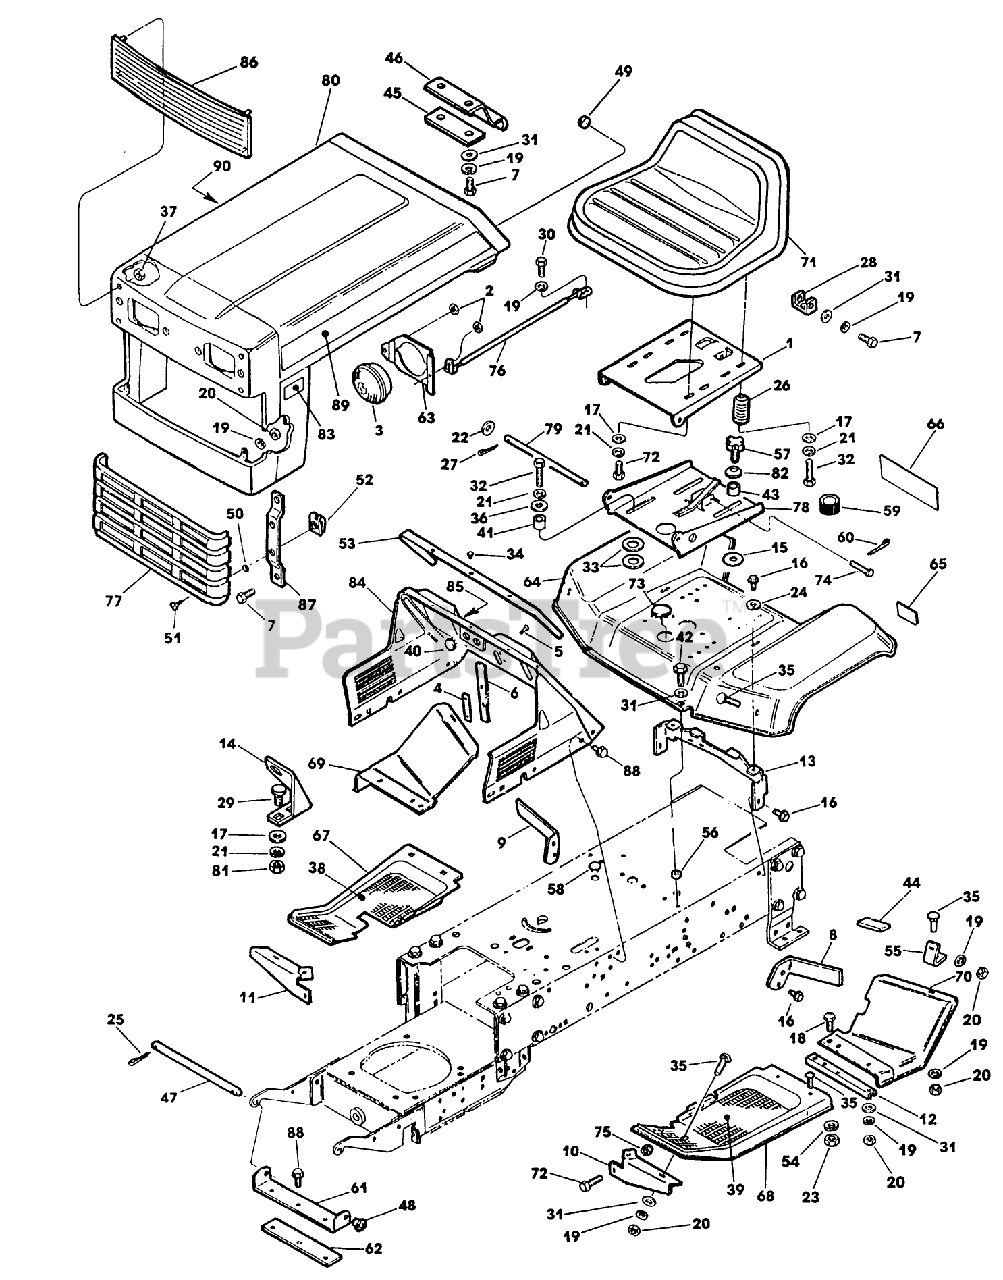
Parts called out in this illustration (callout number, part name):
1	PIVOT AY - SEAT *B
7	SCREW-HH
13	BRACKET-SEAT SUPT
20	NUT
22	WASHER
23	NUT
30	SCREW
32	SCREW
33	WASHER-PLASTIC
43	SPACER
48	BEARING-NYLINER
51	FASTENER-1/4 TURN
54	WASHER
57	KNOB
59	CAP-PROTECTOR
65	REFLECTOR
72	SCREW - HEX
75	NUT
77	INSERT - GRILLE
78	SEAT SUPPORT AY
79	PIN
80	HOOD GRILLE WLDMT *G
81	NUT SS
84	INST PANEL & DECAL
89	DECAL - HOOD LH
